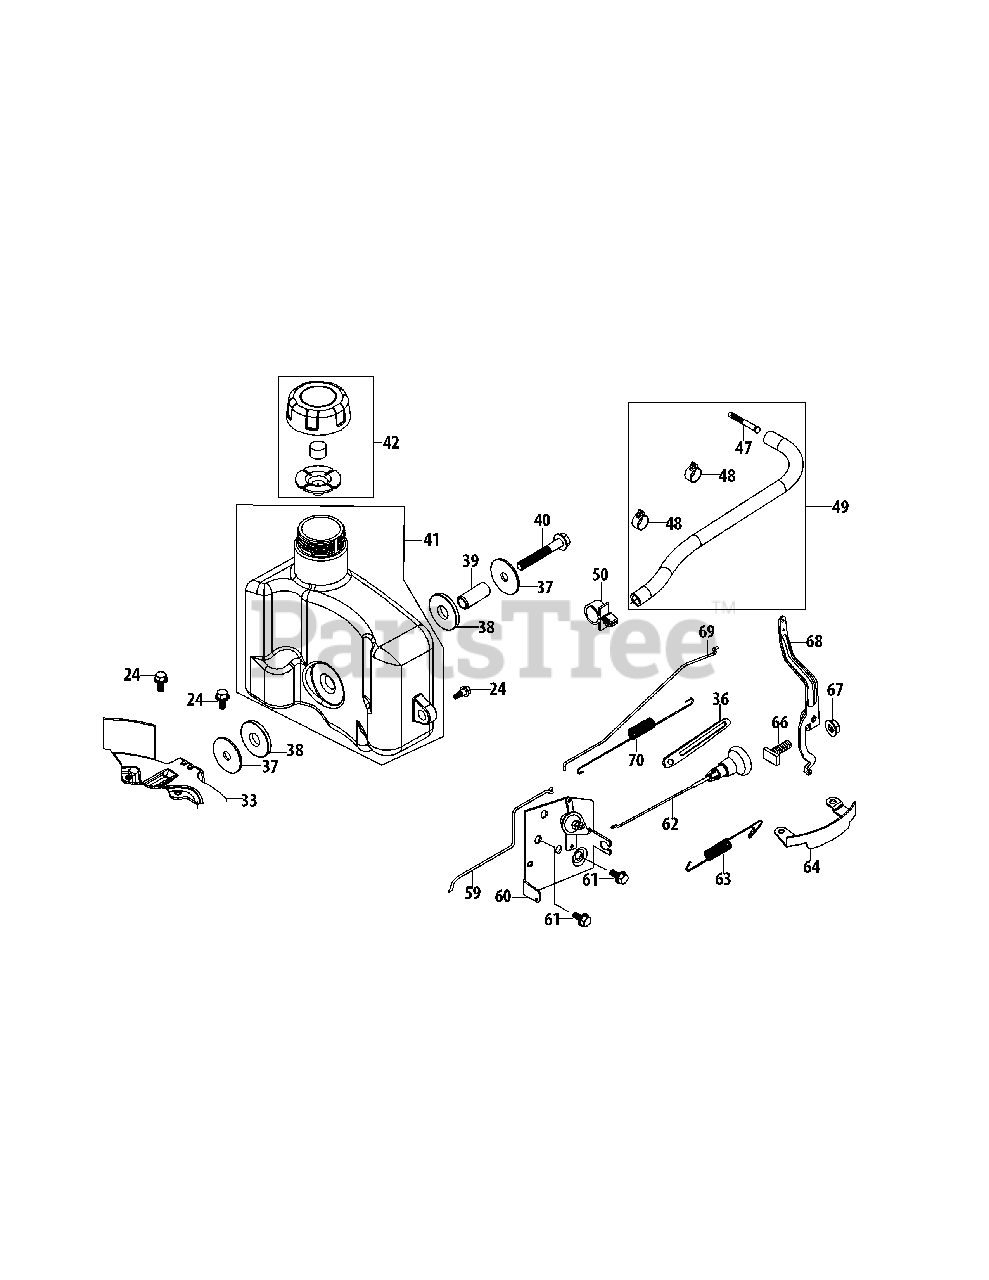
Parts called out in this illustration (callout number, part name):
24	Bolt M6X14
33	Fuel Tank Bottom Bracket
36	Flexible Clamp
37	Fuel Tank Washer
38	Rubber Bushing
39	Fuel Tank Bushing
40	Bolt M8X50
41	Fuel Tank Assembly
42	Fuel Cap Assembly
47	Fuel Filter
48	Fuel Hose Clamp
49	Fuel Line Kit
50	Plastic Support Clamp
59	Choke Linkage
60	Component Bracket
61	Bolt M6X12
62	Choke Control
63	Governor Spring
64	Governor Arm Guard
66	Governor Arm Bolt
67	Governor Arm Nut M6
68	Governor Arm
69	Throttle Linkage Rod
70	Throttle Linkage Spring
